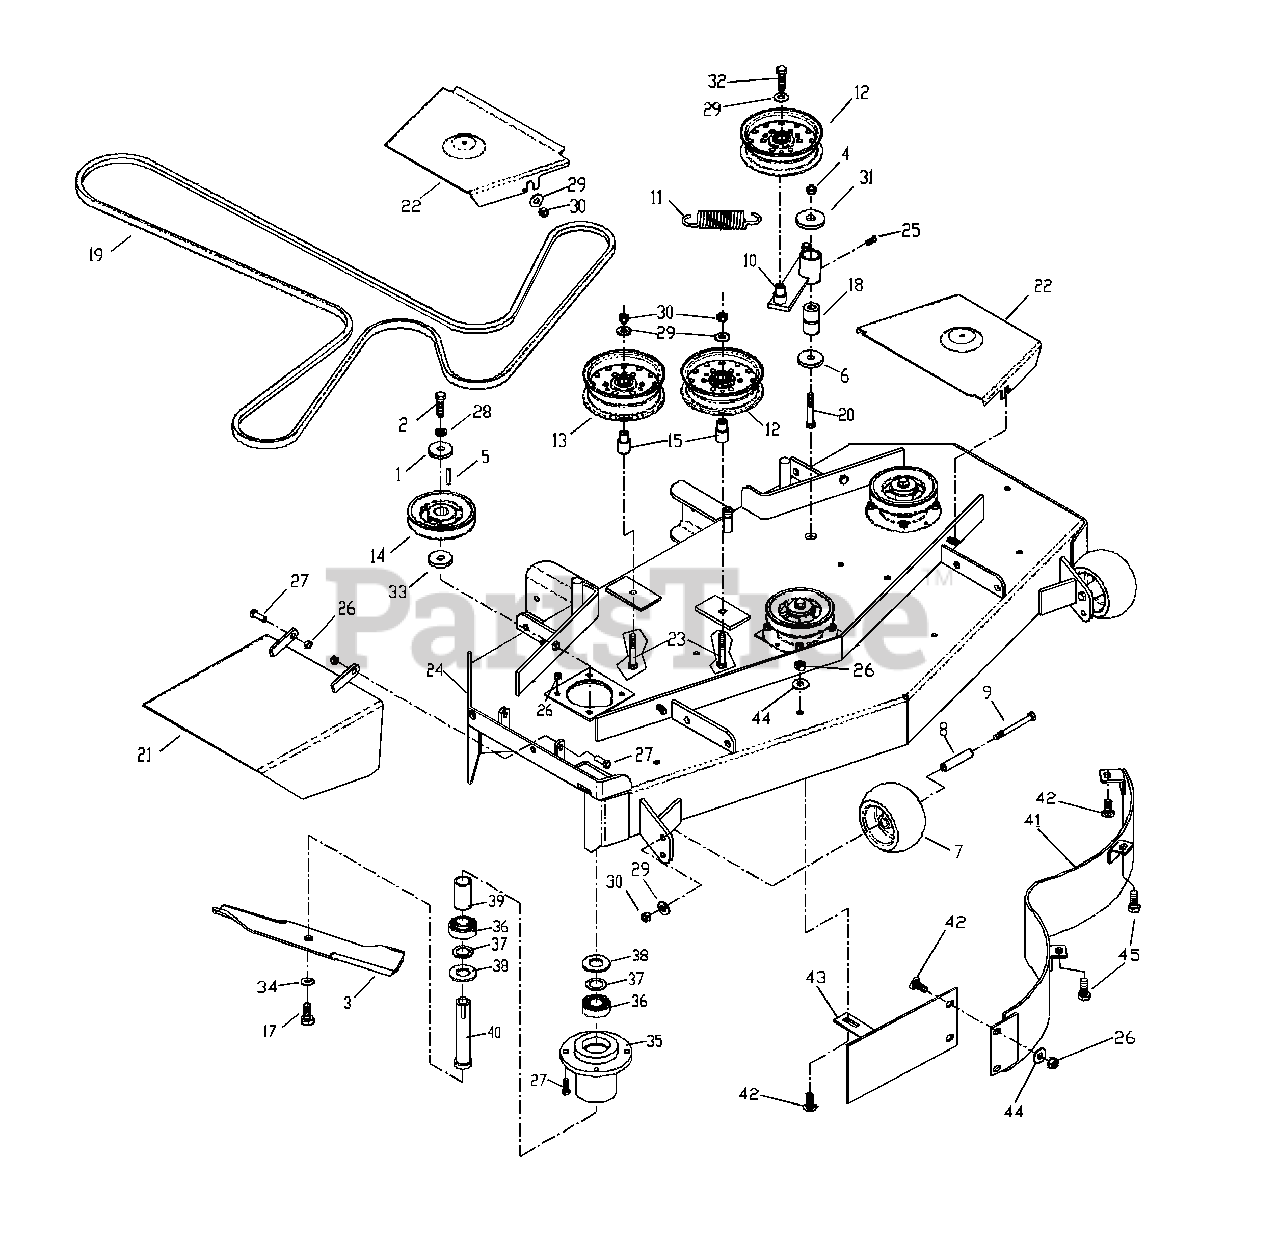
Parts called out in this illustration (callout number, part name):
1	HEAVY WASHER
2	HCS 7/16 X 1.500
3	BLADE 16.250
4	NUT 1/2 NYLOC
5	KEY 1/4 X 1.125
6	SUPPORT WASHER
7	ANTI-SCALP ROLLER
9	HCS 3/8 X 3.500
12	IDLER PULLEY
13	IDLER PULLEY
15	IDLER BUSHING
16	COMPLETE HOUSING
17	HCS 5/16 X 1.250
18	PIVOT BUSHING
19	BELT
20	HCS 1/2 X 3.250
21	DEFLECTOR CHUTE
22	BELT SHIELD
23	HCS 3/8 X 2.500
24	DECK W/DECALS
25	ZERK
26	NUT 5/16 CTR. LOCK
27	HCS 5/16 X 1.000
28	WASHER 7/16 LOCK
29	WASHER 3/8 FLAT
30	NUT 3/8 CTR. LOCK
31	WASHER 1/2 FLAT
32	HCS 3/8 X 1.00 SERR. HD.
33	MACH. BUSHING
34	WASHER 5/8 LOCK
36	BEARING
37	MACH. BUSHING
38	MACH. BUSHING
41	MAIN BAFFLE
42	RHSNB 5/16 X .625
43	CENTER BAFFLE
44	WASHER 5/16 FLAT
45	HCS 5/16 X .750
